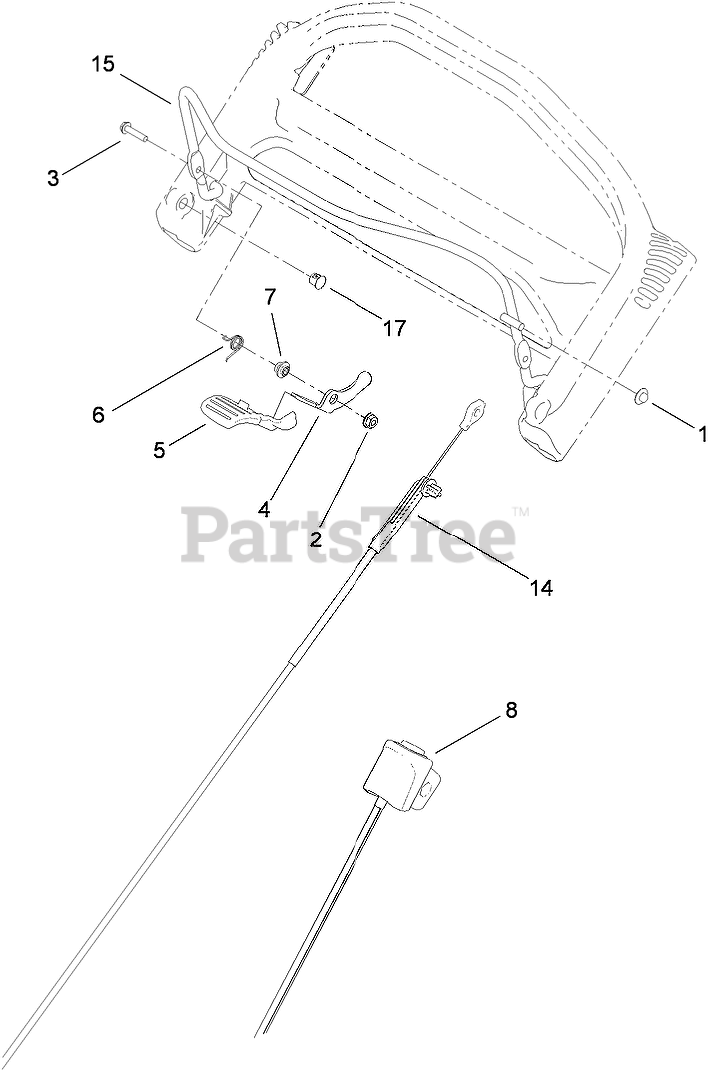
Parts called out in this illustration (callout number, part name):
1	NUT-SPEED
2	NUT-LOCK, FLANGE
3	SCREW-HWH
4	LEVER
6	SPRING-TORSION
7	SPACER
8	SWITCH HOUSING ASM
14	CABLE ASM
15	BAIL-BRAKE
17	Plug-Dome
